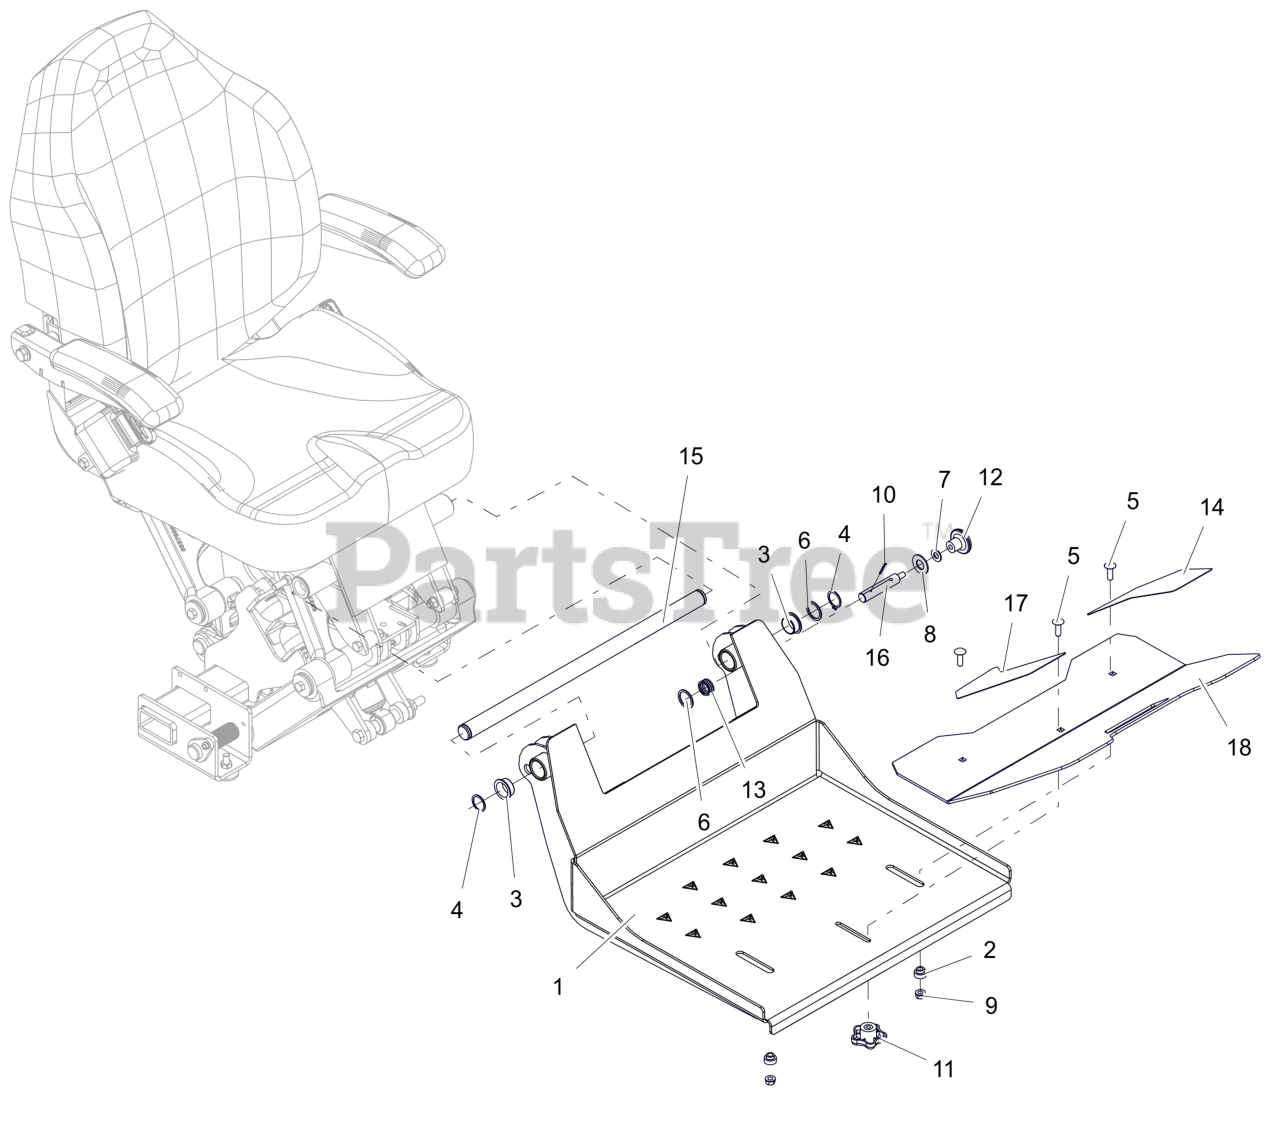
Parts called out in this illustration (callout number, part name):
1	WLDMT- FOOTREST W/SAFETY
2	SPCR, BRG .315X.500X.481X.281
3	BSHG-FLG 1.0X1.125X.50X1.375 R
4	RG-RTNG-EXT 1.00X.042
5	BLT,RHSSN .31-18X1.00 G5 ZCC
6	WSHR-FL-STL 1.01X1.25X0.068 ZCC
7	WSHR,FLT .406X.812X.065 ZCC
8	WSHR-FL-STL 0.649X1.305X0.074 Raw
9	NUT,LK-CTR-FLG .31-18 GF ZCC
10	PIN-COTR .09X1.0 PL
11	KNOB, LOCKING 5/16-18 UNC
12	KNOB, PUSH-PULL .312-18
13	SG-COMP .085X.80X1.00 WLD36
14	KIT, PT300-600 ANTI-SKID Tape
15	SHAFT, PIVOT
16	PIN, FOOTREST LOCK-UP
17	KIT, PT300-600 ANTI-SKID Tape
18	FOOTREST, ADJUSTABLE (RED) W/ SAFETY DECAL
